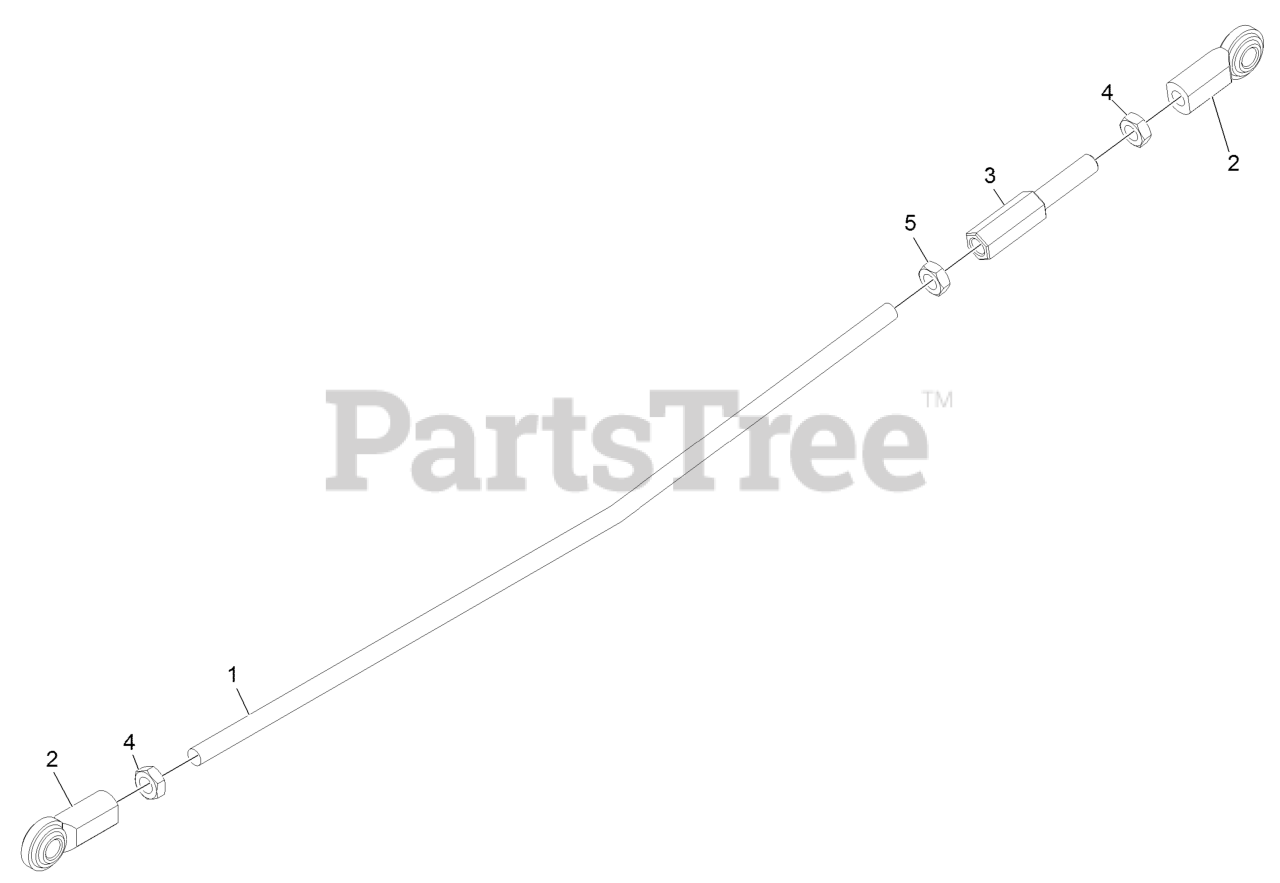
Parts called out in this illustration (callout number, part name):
1	LINK-LOWER, MOTION CONTRO
2	JOINT-BALL, END
3	ROD-ADJUSTMENT
4	NUT-HJ
5	NUT-HEX JAM, LH
